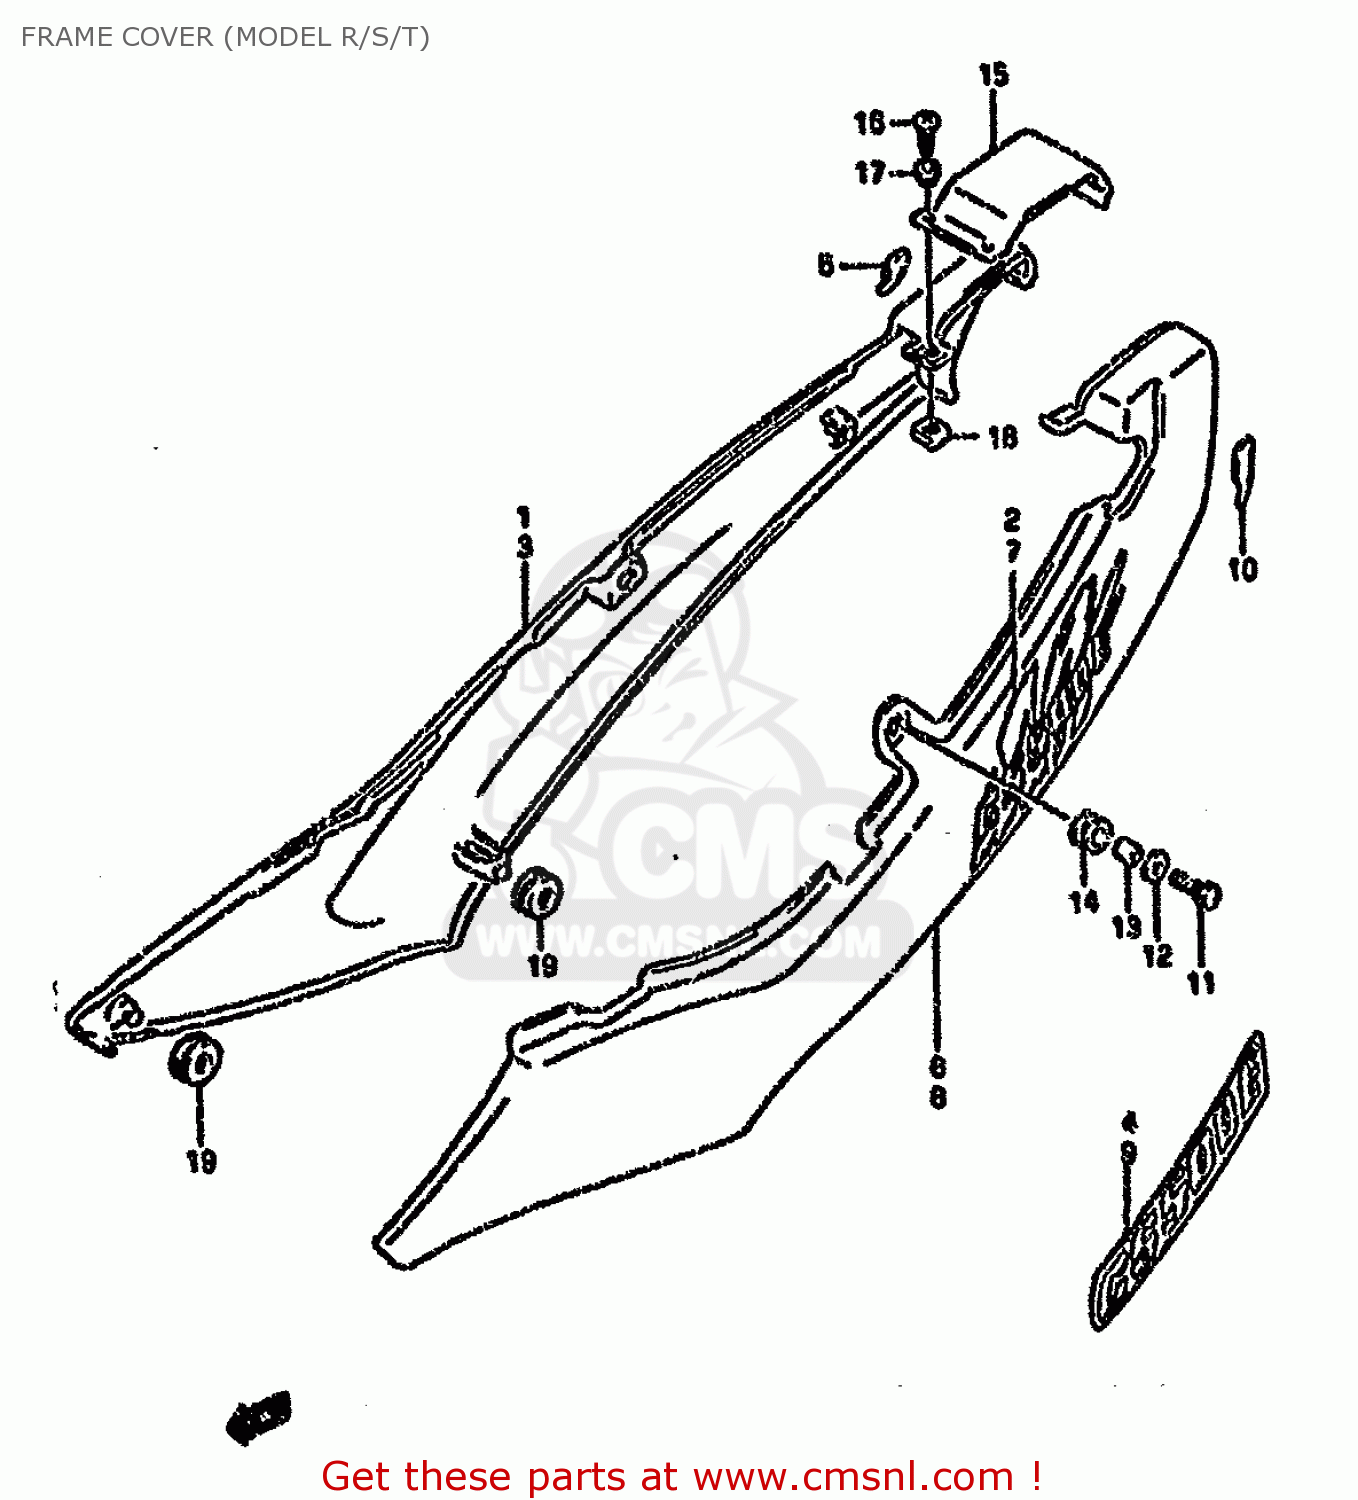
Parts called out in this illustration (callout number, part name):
1	COVER,FRAME,RIGHT
2	EMBLEM,FRAME COVER
3	COVER COMP,FRAME,RIGHT
4	EMBLEM,FRAME COVER
5	PROTECTOR,FRAME COVER,R
6	COVER,FRAME,LEFT
7	EMBLEM,FRAME COVER
8	COVER,FRAME,L(RED)
9	EMBLEM,FRAME COVER
10	PROTECTOR,FRAME COVER,L
11	BOLT(6X20)
12	WASHER
13	SPACER (6.1X9X9)
14	CUSHION
15	COVER,FRAME CTR
16	SCREW L:12
17	WASHER(5.2X14X1.5)
18	NUT
19	CUSHION
